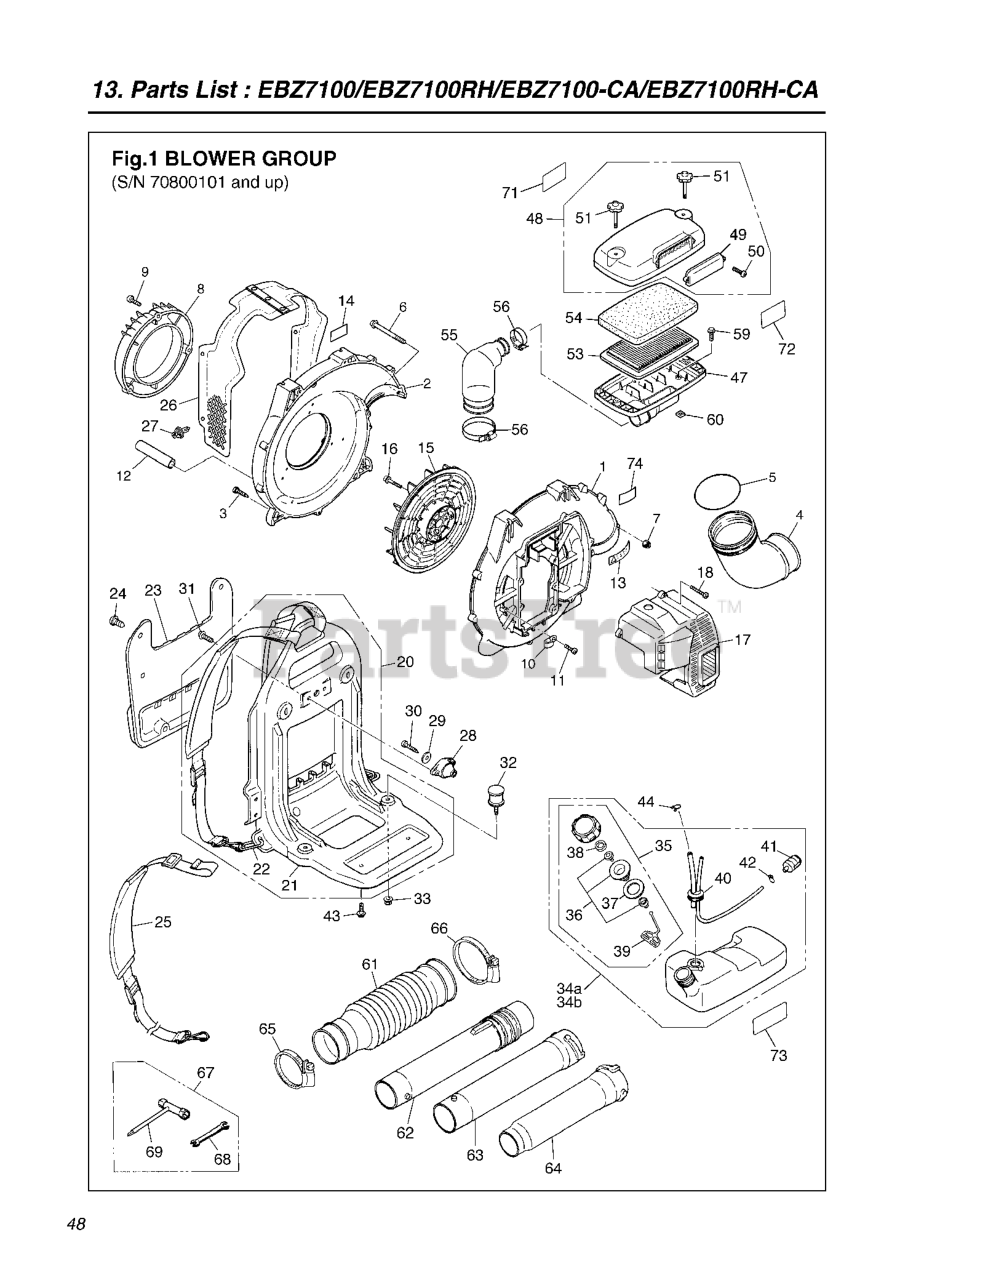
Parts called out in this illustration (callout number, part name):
1	VOLUTE CASE
8	COVER, INLETEB7001
12	TUBE
13	LABEL.CAUTION
14	LABEL, NET
15	FAN
16	BOLT
17	ENGINE COVER
20	FRAME ASSY(RPLS -3500,-3501)
21	FRAME COMP.
22	RING
24	CLIP
25	BAND ASSY. (BUCKLE 275632910)
26	NET COMP (RPLS-T402325430)
27	CLIP
28	DAMPER UPPER
29	WASHER
30	BOLT
32	DAMPER
34A	RP_TANK ASSEM(RPLS T401285100)
35	ASSY FUEL CAP
36	HOLDER-A
40	PIPE COMPLETE
41	FILTER ASSY
42	CLIP
44	CLIP
47	%BODY, CLEANER
48	COVER ASSY
51	KNOB BOLT
53	ELEMENT
54	ELEMENT
56	CLAMP
62	SWIVEL JOINT
64	PIPE, END (RPLS 848L5C65E0)
65	CLAMP
66	CLAMP
67	TOOL-SET
69	SOCKET
